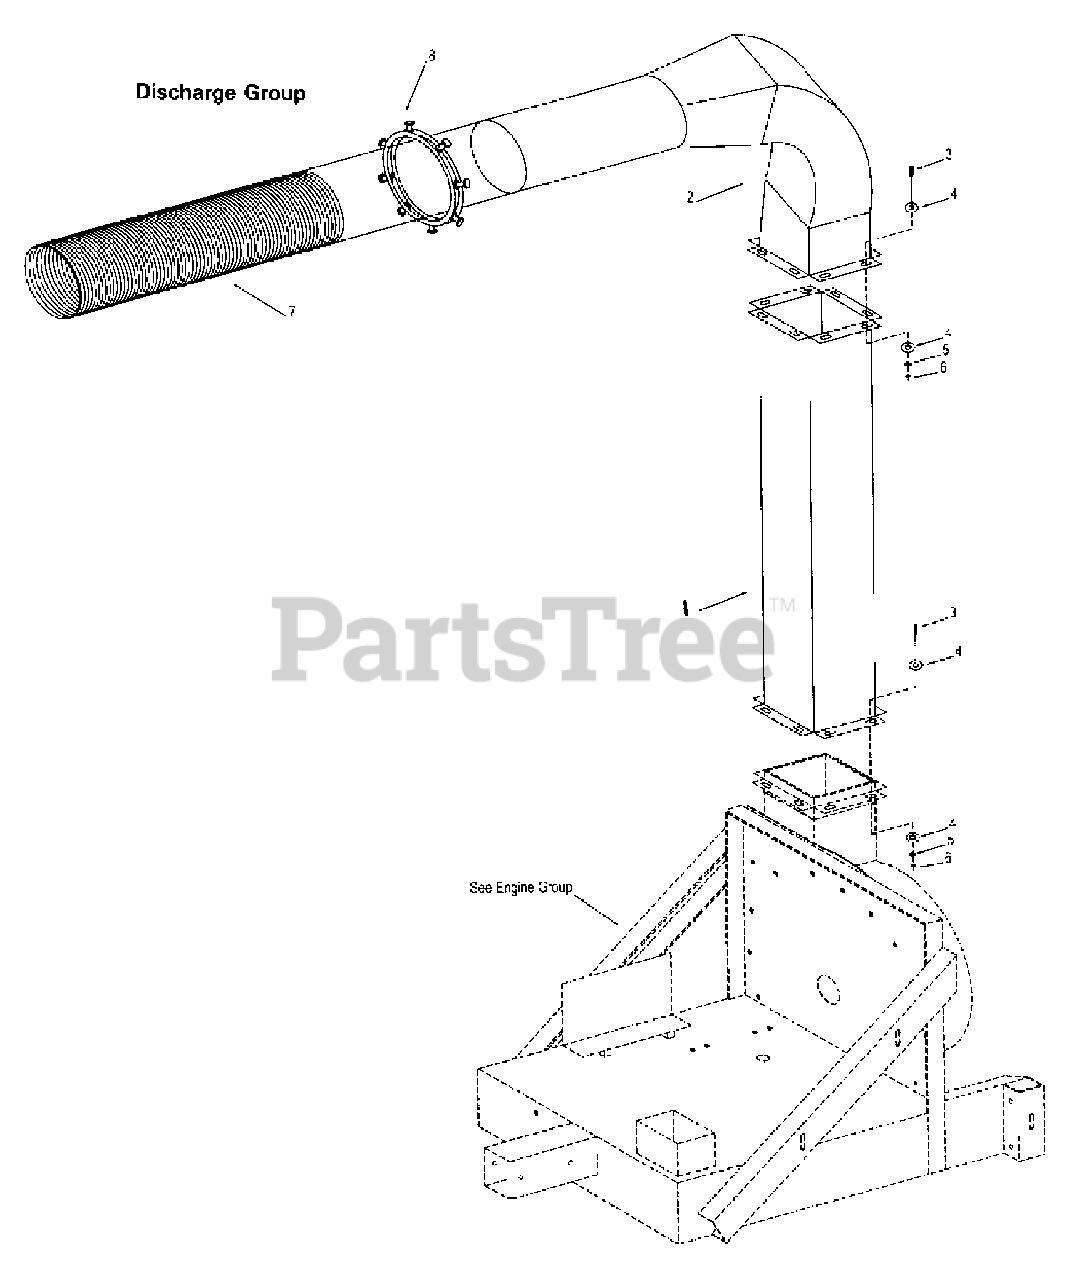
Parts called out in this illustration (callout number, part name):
1	Discharge Stack
2	Discharge Elbow
3	3/8-16 x 1-1/4" Hex Bolt
4	3/8 Flat Washer
5	3/8 Lock Washer
6	3/8-16 Hex Nut
7	Hose, Discharge 8" x 5' Metal
8	Ring, Squeeze 8"
